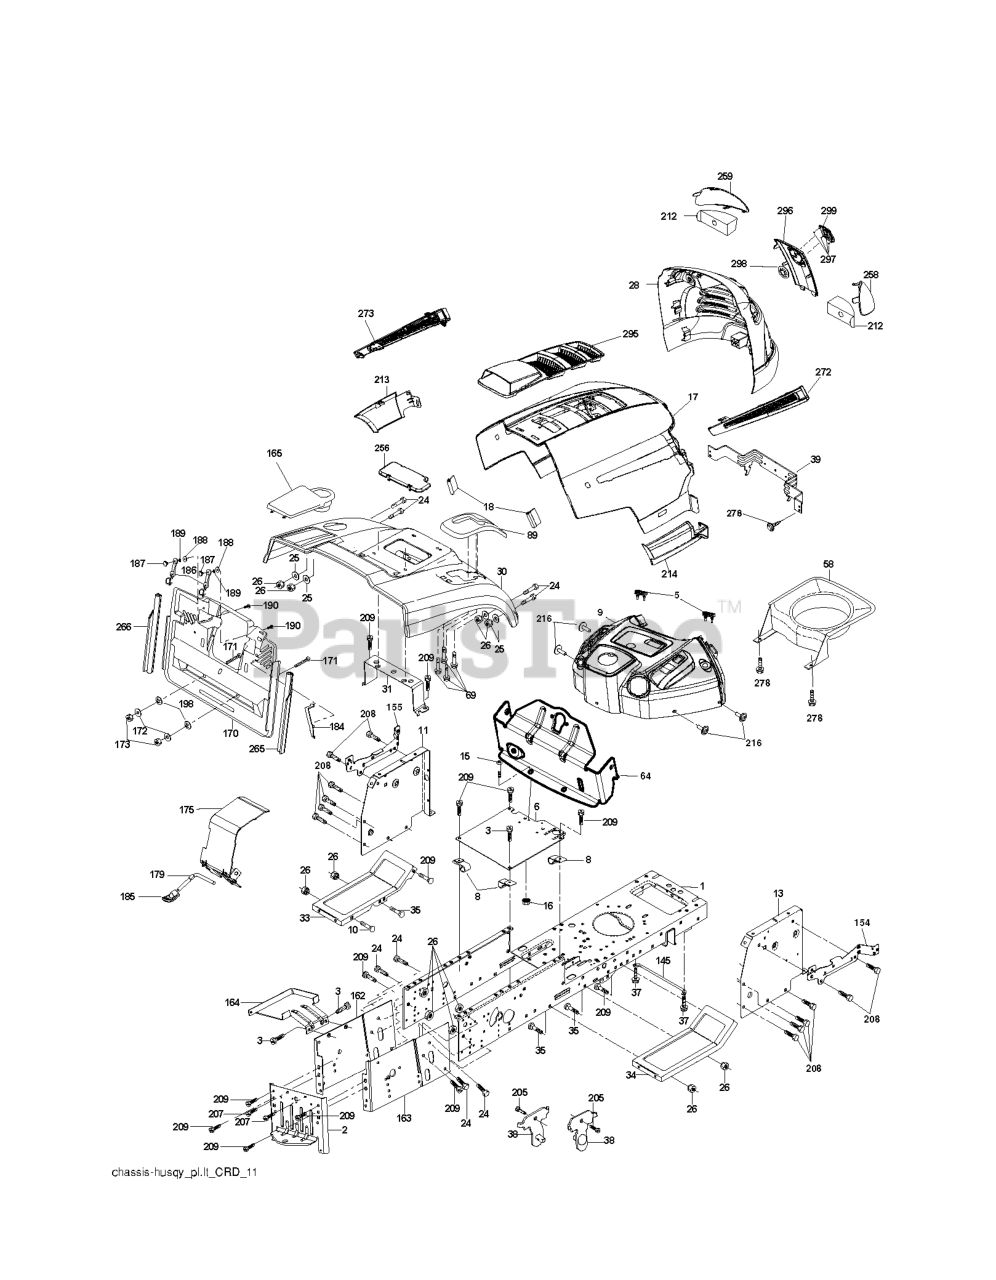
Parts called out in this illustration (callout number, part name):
2	DRAWBAR
3	SCREW 3/8-16X3/4
5	BUMPER DASH
6	PLATE
8	CLIP,INSULATOR
10	BOLT D
11	PANEL.DASH.LH.LTX
13	PANEL ASM, DASH RH
15	Screw, Machine, Truss Head 5/16-18 UNC x 3/4
16	NUT
17	HOOD
18	BUMPER.HOOD.TEX.HUSQVARNA
25	WASHER
26	NUT
28	RP GRILLE/LENS ASM.
30	CONSOLE.CRD.AUTO.GRY
31	BRACKET SUPPORT FENDER
33	FOOTREST PNT LH
34	FOOTREST PNT RH
37	Screw 5/16-18 x 1/2 Hex, Self Tapping 5/16-18 x 1/2
38	BRACKET ASM PIVOT MOWER REAR
39	BRACKET PIVOT
69	SCREW.HI-LO.CONSOLE
89	CONSOLE.CRD.AUTO.GREY.2005
145	ROD.PIVOT.HOOD
162	BRACKET
163	BRACKET EXTEN CHASSIS RH CRD
165	RP.COVER.BATTERY.CRD.GREY
172	WASHER
175	DOOR TRAP
179	ROD PIVOT FBI
184	BRACKET.ACTUATOR.BAGGER.SRD
186	LATCH ASSY
187	WELDNUT
189	LOCKWASHER #10
190	SCREW
207	SCREW, 5/16-18 X 1/2
208	SCREW 3/8-16X1/2
209	SCREW, 3/8-16X3/4
212	INSERT REFLECTIVE
213	SKIRT SIDE LH
214	SKIRT SIDE RH
216	SCREW HEXWSHR 1/4-20X3/4
256	COVER FENDER CRD
258	LENS.HUSQVARNA LT.RH
259	LENS.HUSQVARNA LT.RH
265	SEALING
266	SEALING
278	SCREW
295	VENT TOP HOOD
296	TRIM
297	CLIP.RETAINER.TINNER.
298	NUT PUSH M
299	RP LOGO
